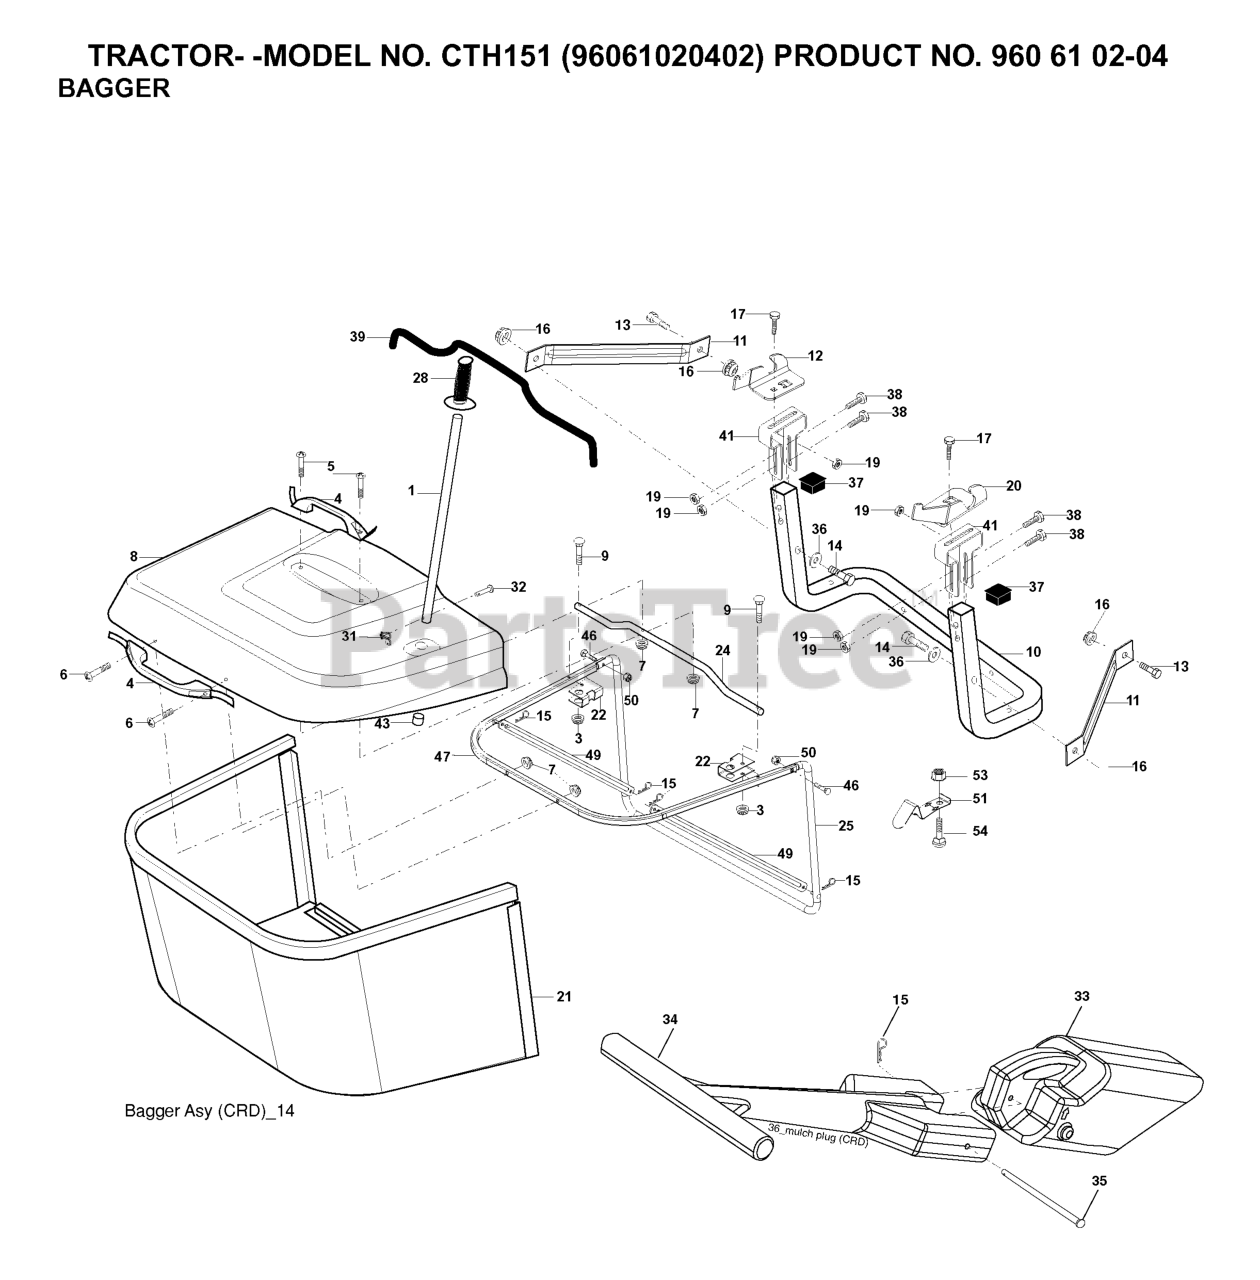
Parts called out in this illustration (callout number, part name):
1	TUBE HANDLE
3	NUT T
4	HANDLE.BAGGER.W/LVRS.BLK.CRD
5	SCREW.PAN.HEAD
6	REPL BY 532 75 00-29
8	COVER.PNT.BGR.CRD.WSLOTS.MS668
9	Bolt Carriage 1/4-20 x 2.25d x Gr.5
10	TUBE
11	BRACKET.SUPPORT.UPPER.BAG.CRD
12	BRKT PIVOT
14	BOLT-HEX EAK
15	RETAINER-SPRNG RB
16	NUT LOCK FLG 3/8-16 UNC
17	RP BOLT 5/16-18 X3/4 ZN/YEL GR
19	NUT LOCK HEX FLANGE 5/16-18
20	BRKT.PIVOT.RH.CRD
21	BAGGER.ASM.CRD.2007
22	BRKT.SIDE.BAG.CRD
24	TUBE.PIVOT.BAG.CRD.BLACK
25	PIPE
28	GRIP.HANDLE.BLACK
31	RETAINER CLIP
32	RIVET,DRILLED
33	PLUG.MULCHER.92 CRD
34	HANDLE.MULCHER.92.CRD (2 2)
36	WASHER
37	Plug Support Bagger CRD
38	BOLT.5/16-18X2.5
39	SEAL.TRIM.37'
41	BRKT.VERT.ADJ.BAGGER.CRD
43	PLUG, TUBING END
46	BOLT.CARRIAGE.5/16-18
47	PIPE
49	ROD
50	NUT.71038.31-18.HEX.NYLOCK
51	LATCH
53	NUT
54	BOLT
